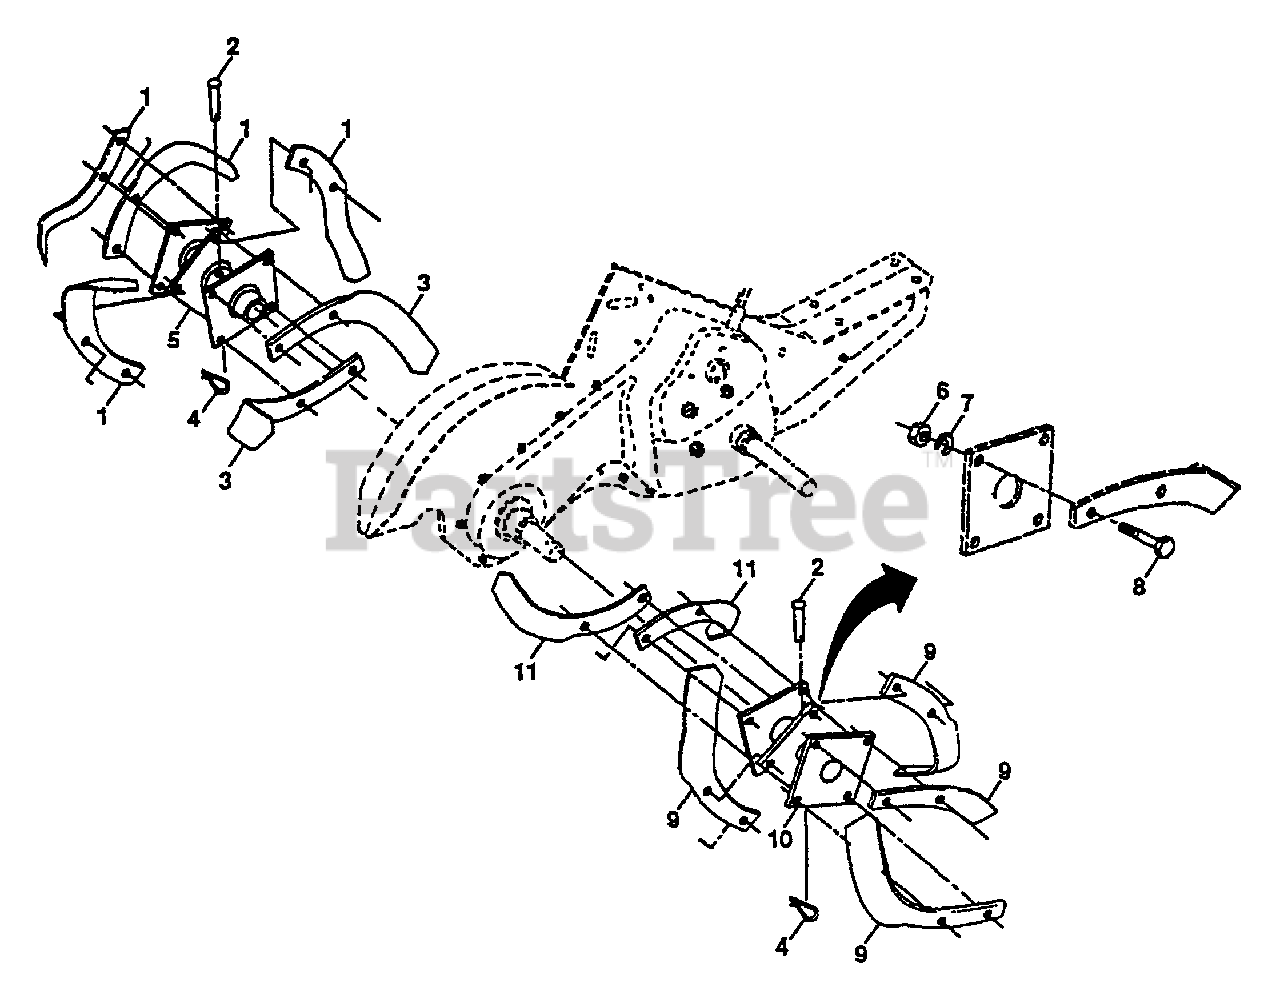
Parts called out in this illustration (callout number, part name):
1	Tine, Outer, LH.
2	Clevis Pin
3	Tine, Inner, L.H.
4	Clip, Hairpin
5	Assembly, Hub and Plate, LH.
6	Nut, Hex 3/8-24
7	Washer, Lock 3/8
8	Bolt, Hex 3/8-24 x 1
9	Tine, Outer, R.H.
10	Assembly, Hub and Plate, R.H.
11	Tine, Inner, R.H.
